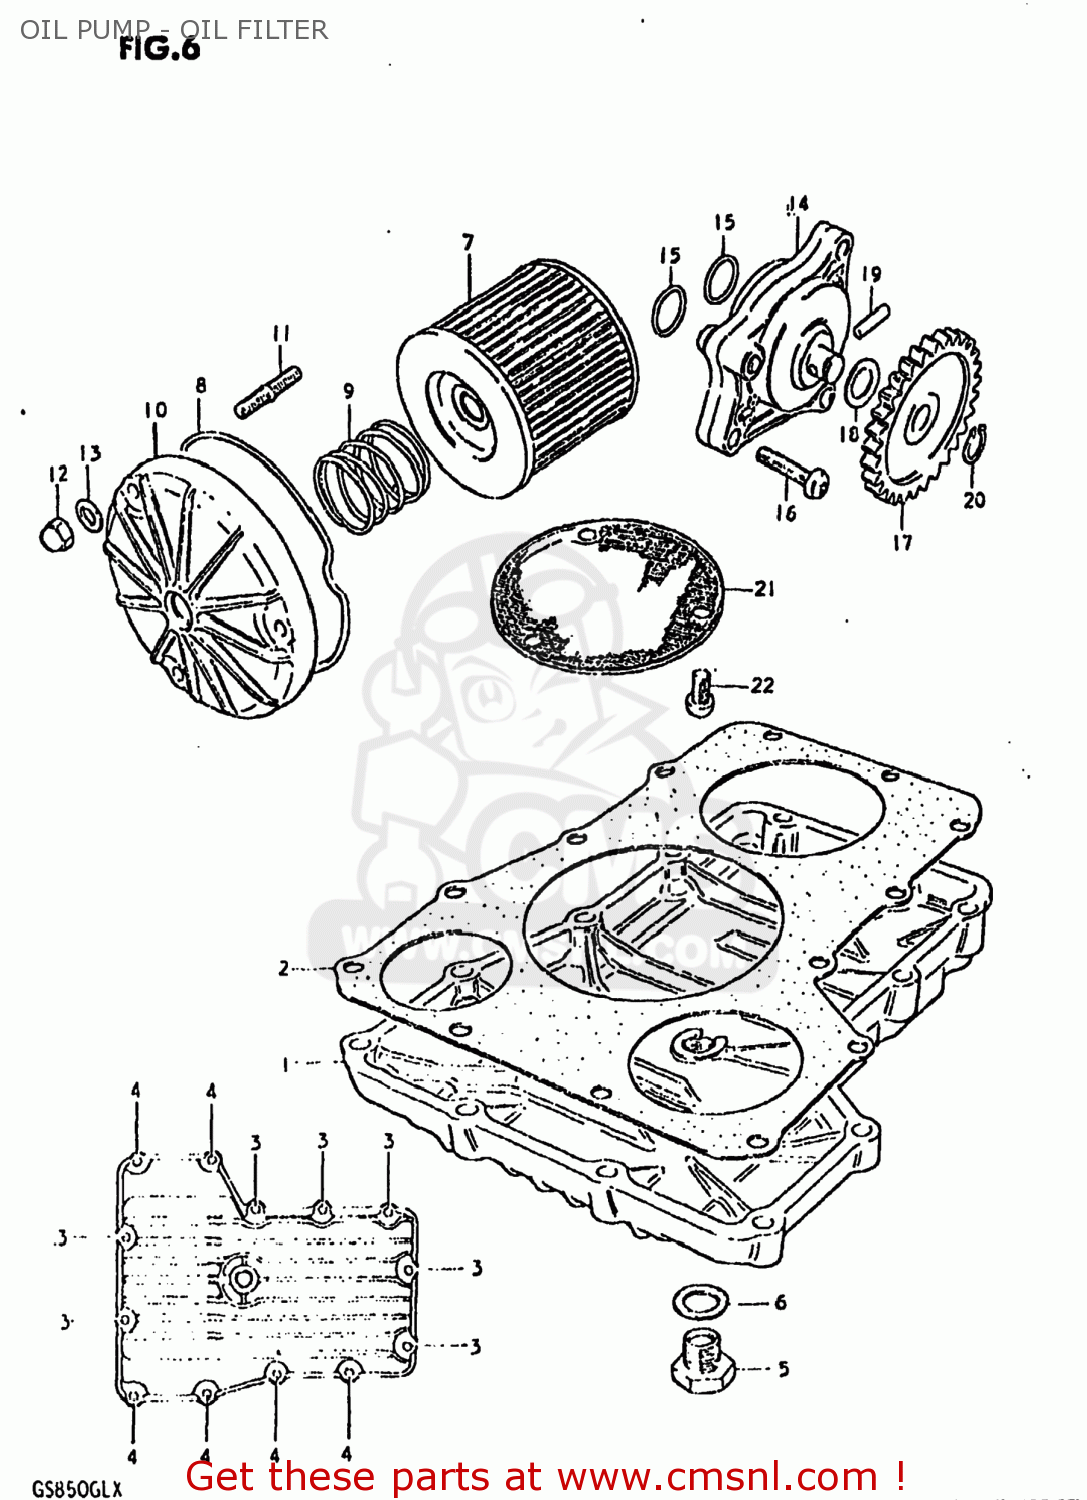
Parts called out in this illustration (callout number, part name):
1	PAN,OIL
2	GASKET,OIL PAN (MCA)
3	BOLT
4	BOLT
5	PLUG
6	GASKET(14X19.2X2) (NAS)
7	FILTER ASSY,ENGINE OIL
8	O RING,OIL FILTER CHAMBER CAP
9	SPRING
10	CAP,OIL FILTER
11	STUD 6X20
12	NUT
13	WASHER
14	PUMP ASSEMBLY,OIL
15	O RING(D:1.9,ID:13)
16	SCREW
17	GEAR,OIL PUMP DRIVEN
18	SHIM
19	PIN(4X15.8)
20	CIRCLIP
21	STRAINER,ENGINE OIL
22	SCREW 6X12
